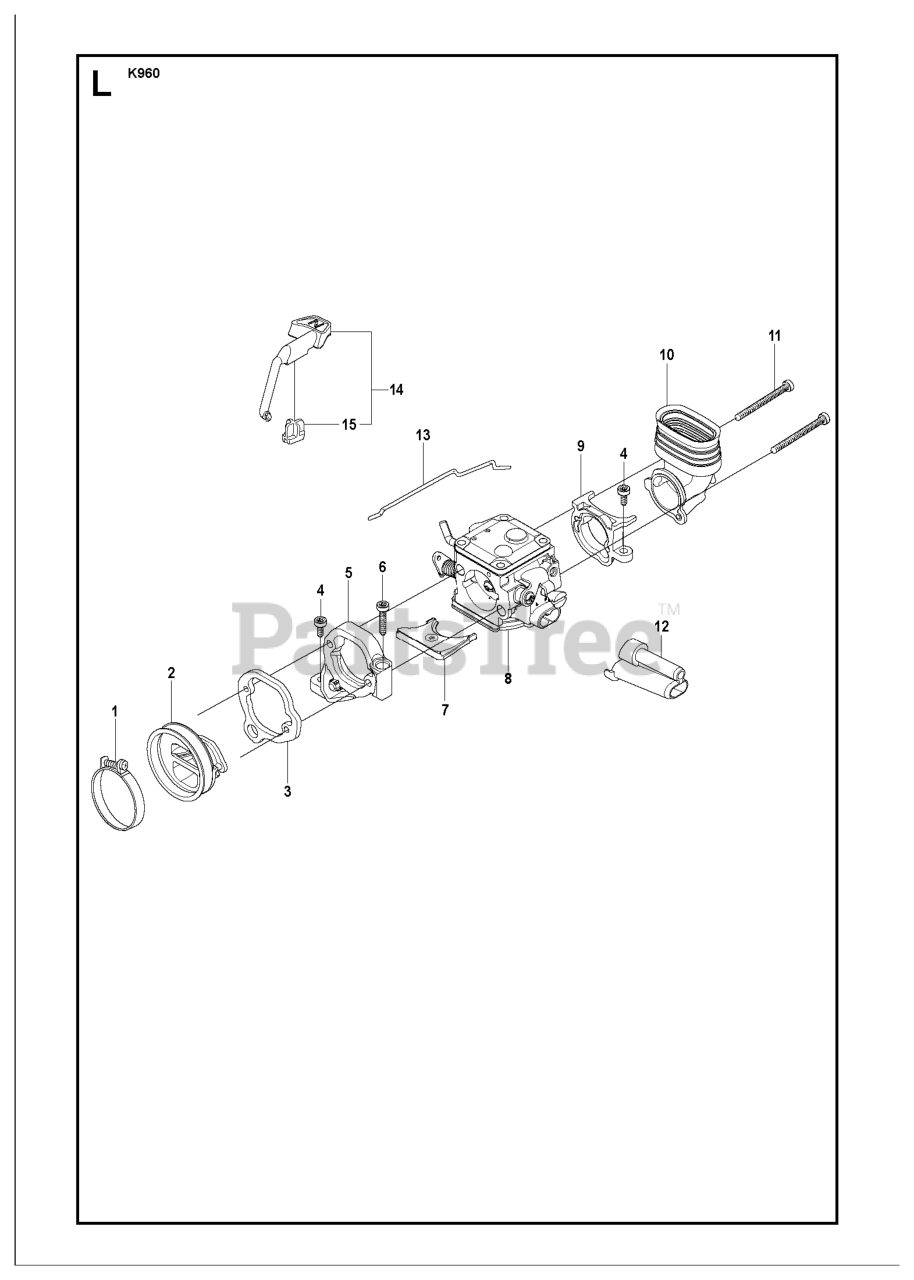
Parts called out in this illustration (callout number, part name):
1	HOSE CLAMP
2	INLET PIPE
8	CARBURETOR ASSY RWJ-3
10	INLET BEND
11	SCREW
12	CHISEL GUIDE
13	THROTTLE ROD
14	CHOKE CONTROL
